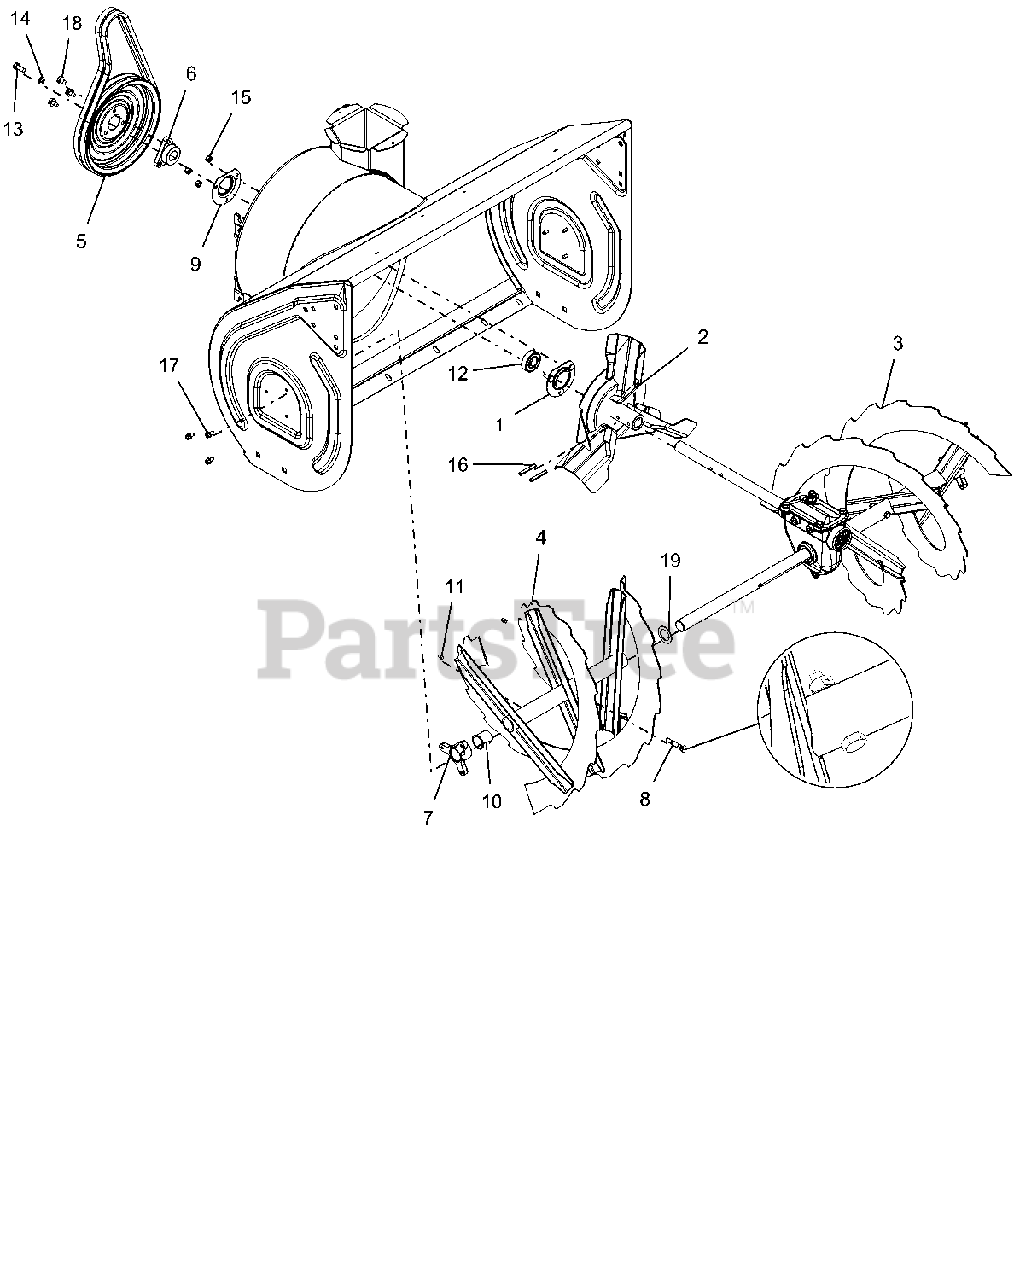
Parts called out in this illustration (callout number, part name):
1	BEARING FLANGE
2	IMPELLER, 3 BLADE-14"
3	RAKE, LH-32"(1 ID X 15.75 OD)
4	RAKE, RH-32"(1 ID X 15.75 OD)
5	PULLEY, SPIN FORM DUAL GROOVE
6	PULLEY HUB, D-BORE .87 PRO
7	BUSHING, RAKE SHAFT 1"
8	SHEAR BOLT SERVICE ASSEMBLY
9	BEARING FLANGE
10	BSHG-FLG SPLIT NYLINER 1.0" HP
11	ZERK,FITTING .25X.125 DRIVE IN
12	BRG-BALL .876X1.75X.50 RSTFP
13	BLT-HEX .31-24X.75 YWZC GR5
14	WSHR-LK .312X.097 HVY YWZC
15	@NUT-LK-CTR .25-20 YWZC
16	PIN-ROLL .250X1.75
17	SCR-TAP .25-20X.50 HWH TR YWZ
18	@SCR-TAP .31-18X.50 HWH TR YWZ
19	WSHR-FL-STL 1.010X1.505X.062YZ
